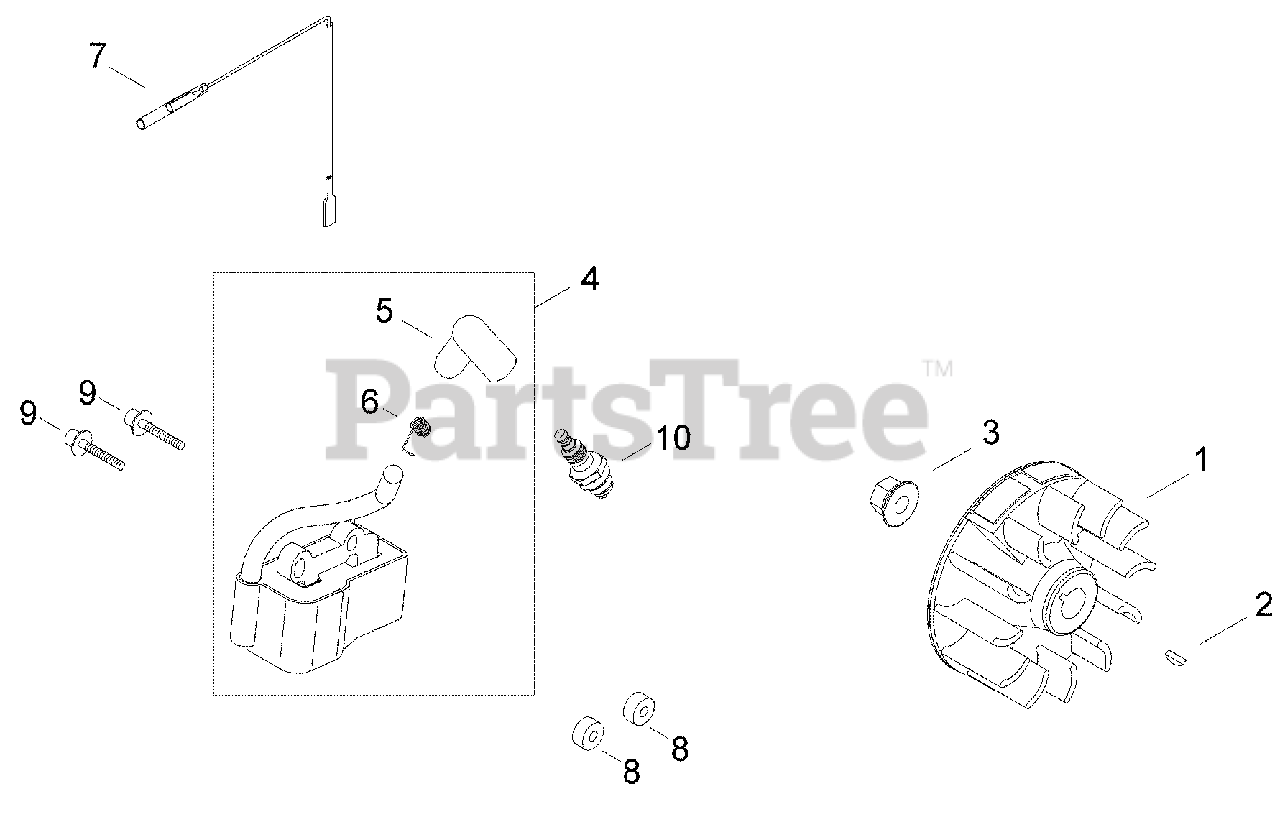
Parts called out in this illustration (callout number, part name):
1	FLYWHEEL
2	KEY - 3X10
3	NUT - 8
4	IGNITION COIL ASSY
5	CAP, SPARK PLUG
6	TERMINAL, SPARK PLUG CAP
7	LEAD - IGNITION
8	INSULATOR
9	SCREW - 4X26
10	SPARK PLUG -- CMR-5H
